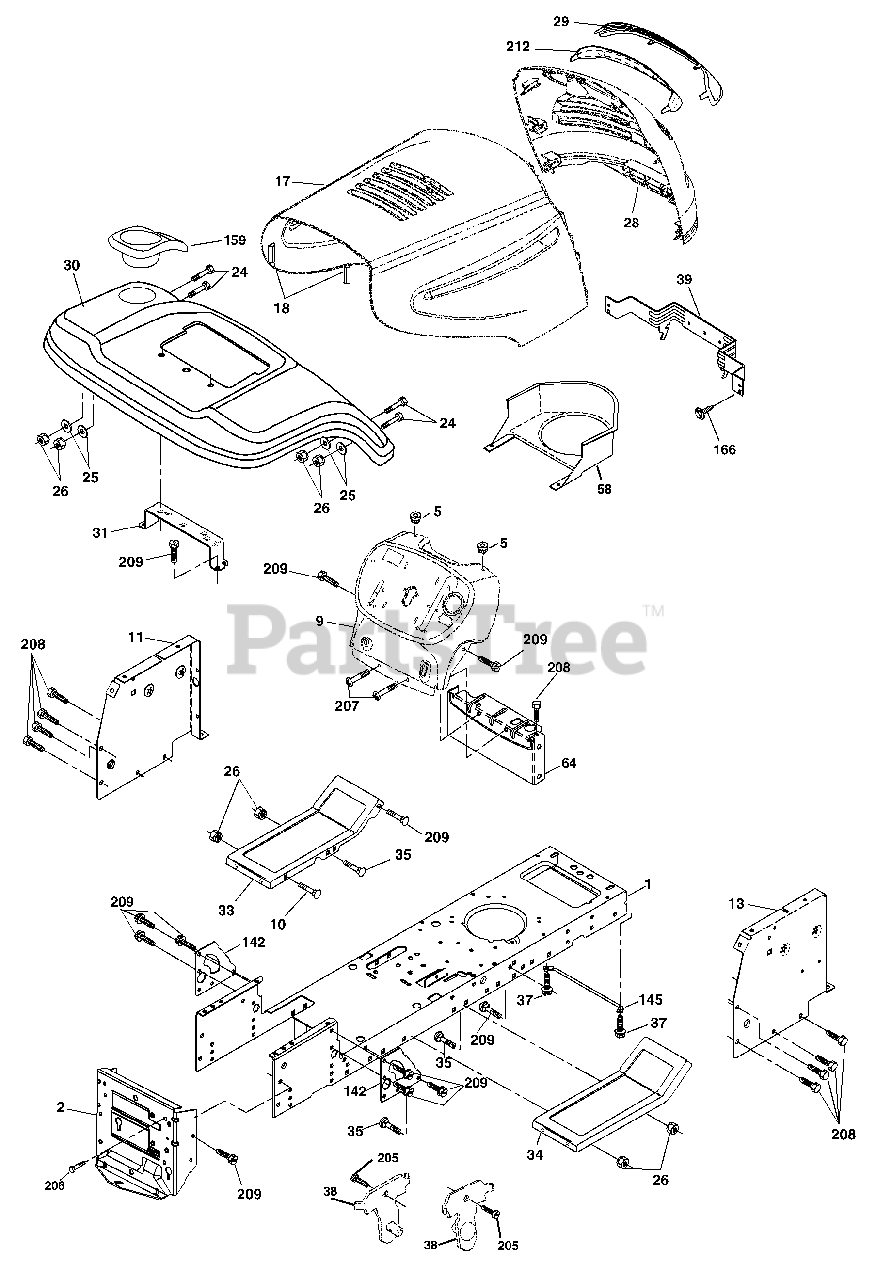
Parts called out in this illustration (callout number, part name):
1	Chassis
2	Drawbar
5	Bumper Hood/Dash
10	Bolt Carriage 3/8-16 x 1
11	Panel Dash Lh
12	Clip Tinnerman
17	Hood
18	Bumper Hood
24	Bolt Fin Hex 3/8-16 x 1 Gr. 5
25	Washer 13/32 x 13/16 x 12 Ga.
26	Nut Lock Hex W/Ins 3/8-16 unc
28	Grille Asm.
29	Lens
31	Bracket Support Fender
33	Footrest Pnt Lh
34	Footrest Pnt Rh
35	Bolt Rdhd Sht Sqnk 3/8-16 x 3/4
37	Screw Thdrol 6/16-18 x 1/2 TYT
38	Bracket Asm. Pivot Mower Rear
39	Bracket Pivot
58	Duct Air Engine
64	Dash Lower STLT
142	Plate Reinforcement STLT
145	Rod Pivot Chassis/Hood
159	Cupholder
166	Screw HWHD Hi-Low # 13-16 x 5/8
205	Screw Thdrol 3/8-16 x 1/2
206	Bolt Shoulder 5/16-18
207	Screw Thdrol 5/16-18 x 1/2
208	Screw Thdrol 3/8-16 x 1/2
209	Screw Hexwsh Thdr 3/8-16 x 3/4
212	Insert Lens Reflect
